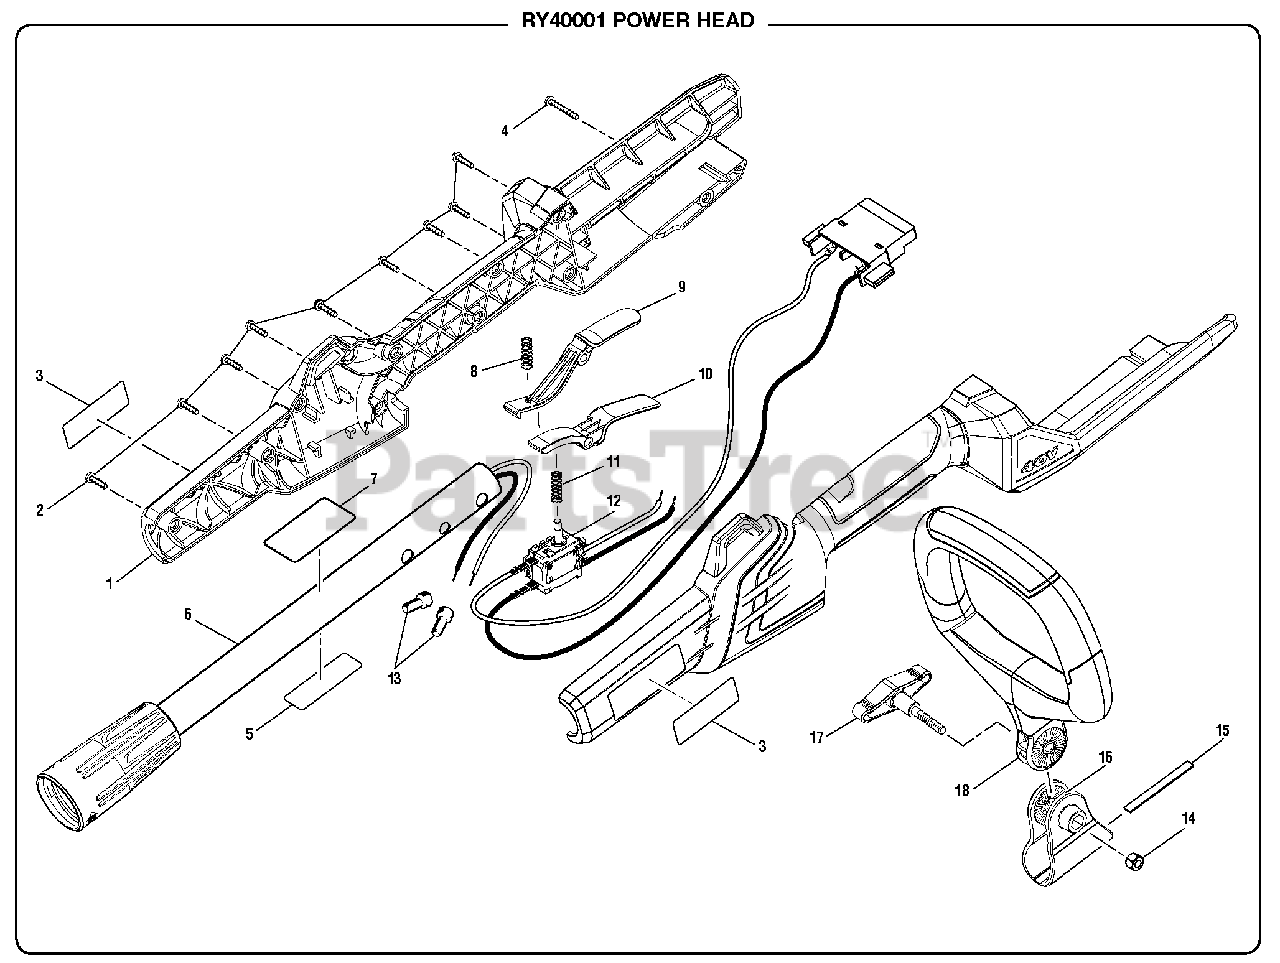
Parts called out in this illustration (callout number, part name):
1	Rear Handle Assembly
2	Screw (M4 x 14 mm, T15 Torx Pan Hd.))
3	Logo Label
4	Screw (M4 x 30 mm, T15 Torx Pan Hd.)
5	Data Label
6	Upper Tube Assembly
7	Warning Icon Label
8	Compression Spring (Trigger Lock)
9	Lock Off Button (Trigger Lock)
10	Switch Trigger
11	Compression Spring (Trigger)
12	Switch and Contact Plate Assembly
13	Wire Connector
14	Hex Nut (M6)
15	Handle Bracket Spacer
17	Handle Knob Assembly
18	Auxiliary Handle Assembly
